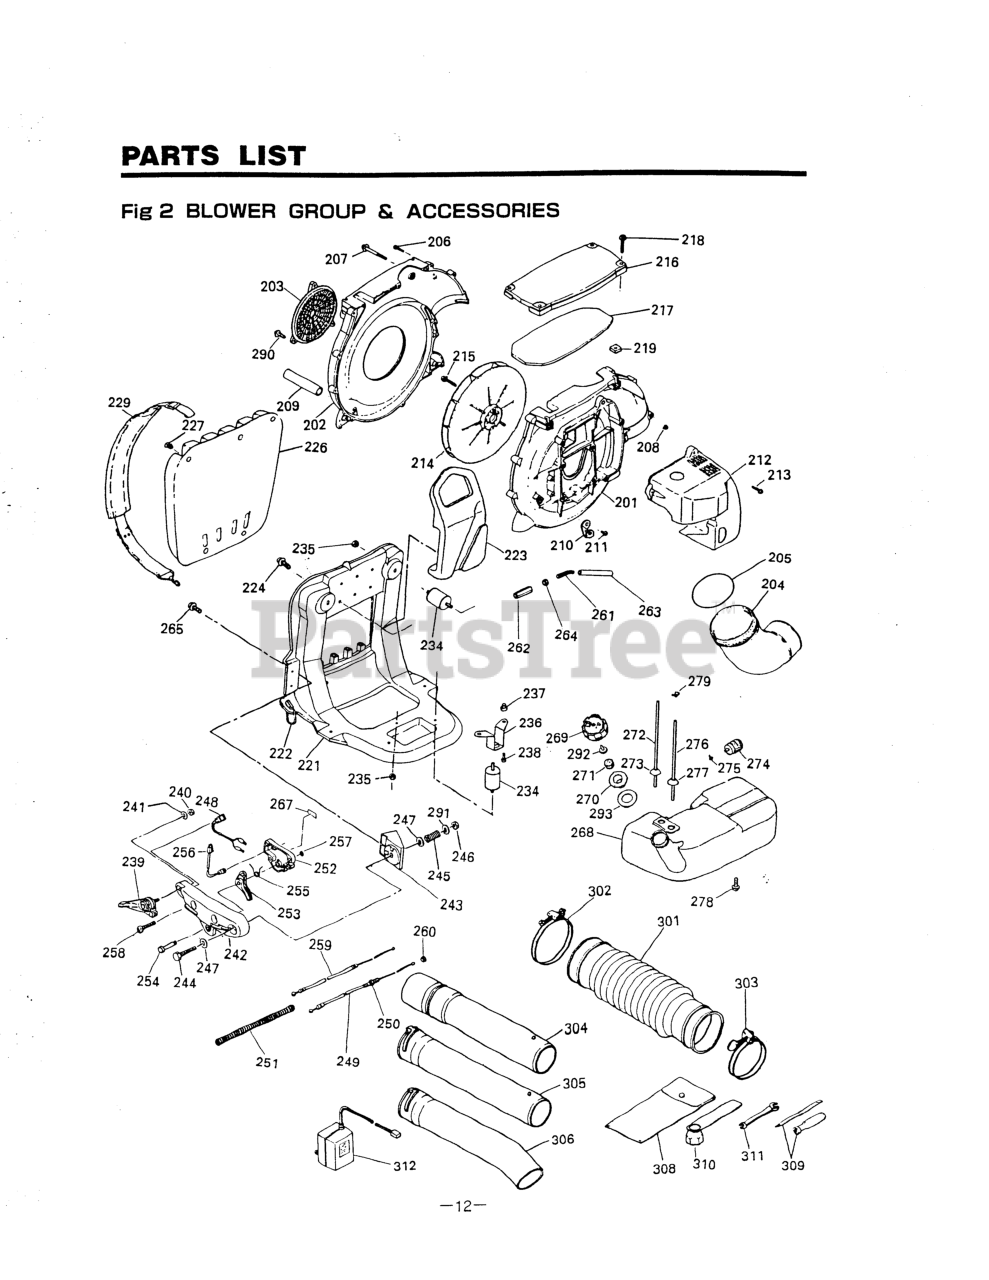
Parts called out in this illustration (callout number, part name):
201	CASE, VOLUTE
202	COVER, VOLUTE
203	NET, GUARD (RPLS-12222)
205	O-RING
206	SCREW
207	SCREW (RPLS 3490-11171)
210	BRACKET
211	SCREW (RPLS -16120)
212	COVER, ENGINE (RPLS-11210)
213	SCREW (RPLS -11221)
214	FAN (REPLACES 3490-12110)
216	COVER (RPLS -13111)
217	COVER, PACKING
218	SCREW
219	NUT
221	FRAME COMPLETE
222	RING (USE -21121)
223	HANGER (RPLS -21210)
226	PAD (RPLS -21310)
227	CLIP (RPLS 3490-21320)
235	NUT, M6 X 5
236	BRACKET (RPLS -22510)
237	WASHER
238	BOLT, M5 x 20
239	LEVER, THROTTLE
240	NUT (B)
241	WASHER, M5x.8(RPLS 01624-20508
243	BRACKET
244	BOLT
245	SPRING
246	NUT, M6 X 5
247	WASHER, PLANE(USE 01640-20816)
248	SWITCH, STOP
249	CABLE COMP,THROTTLE EB441
250	NUT, M6 X 5
251	TUBE (USE 5548-73310)
253	LEVER
256	SWITCH ASSEMBLY
257	RING, SNAP, M4
258	SCREW
259	CABLE COMP, CHOKE
260	NUT, M6 X 5
261	PIPE (RPLS -83210)
263	TUBE (RPLS -83310)
264	NUT, M6 X 5
265	BOLT
267	LABEL, ARM
269	CAP ASSY (RPLS -23202)
272	PIPE (RPLS 3490-23410)
273	GROMMET
274	FILTER ASSY
275	CLIP (REPLACES 2841-31280)
276	PIPE ASSEMBLY
277	GROMMET
278	SCREW (RPLS -23610)
279	CLIP
290	SCREW (RPLS -16120)
291	WASHER
293	PACKING (RPLS -85321)
301	HOSE, FLEXIBLE
302	2756-51510 (RPLS. 07280-09832)
304	JOINT, SWIVEL
305	PIPE, EXTENSION
306	PIPE, BENT
308	TOOL SET (RPLS-91000)
309	SCREWDRIVER
311	SPANNER, 8 X 10 (RPLS 2540- )
312	CHARGER, FOR 120V AC
